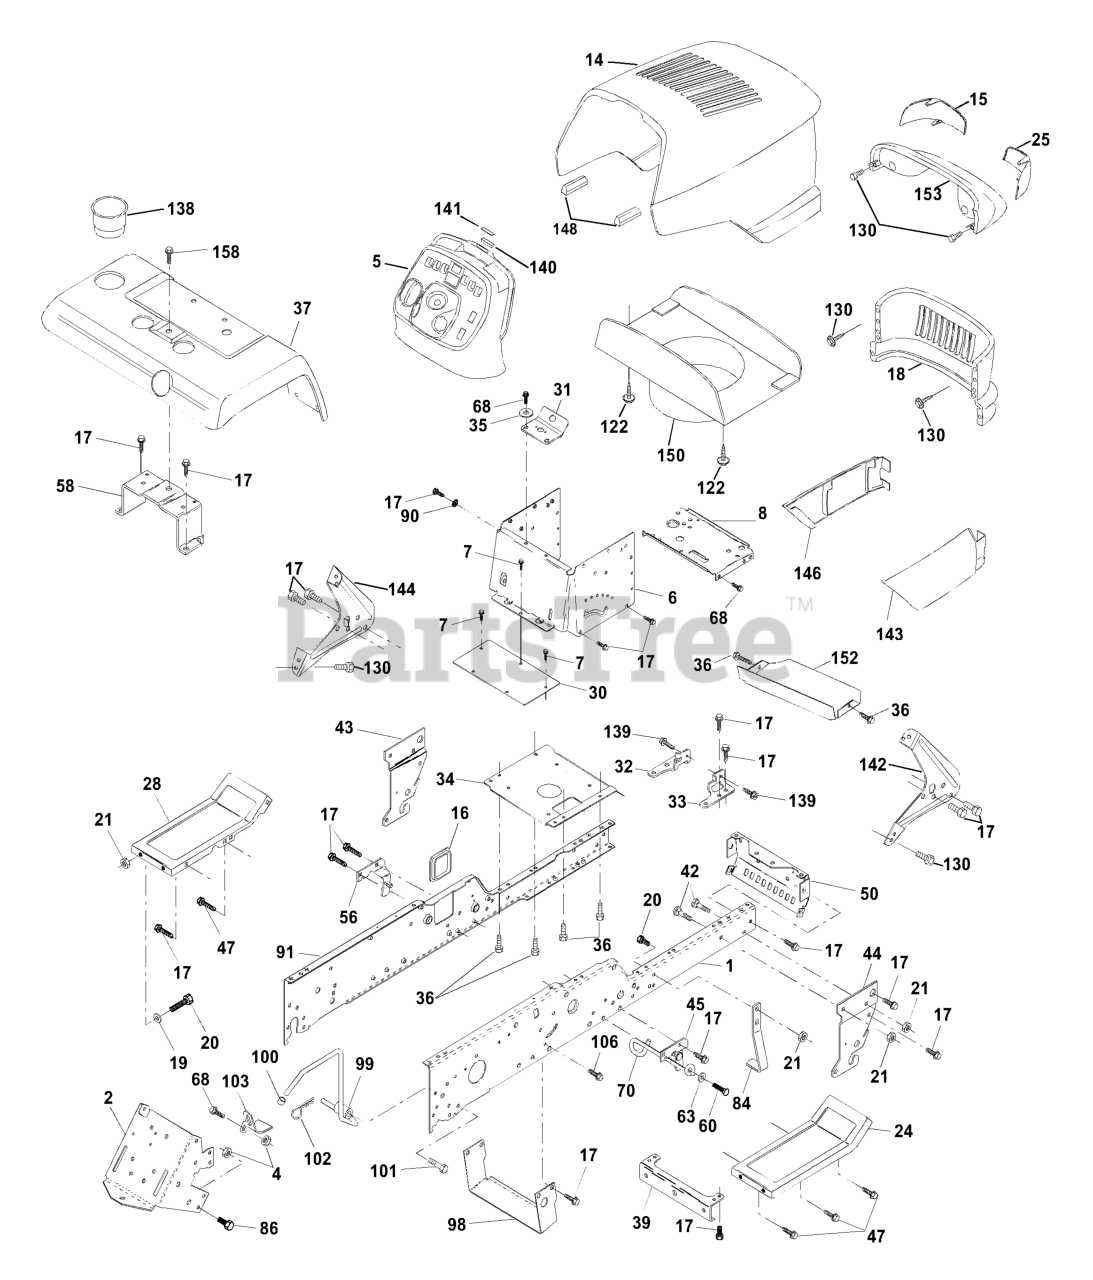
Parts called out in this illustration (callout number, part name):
1	RAIL, FRAME RH
2	DRAWBAR, GT
4	Nut, Lock Hex 7/16 Unc
5	DASH.STEALTH.YTGT.2CYL.BLK
6	DASH VGT, LOWER
7	SCREW
8	SUPPORT, BATTERY
14	HOOD ASM.
15	LENS LH
16	COVER ACCESS
17	SCREW 3/8-16X3/4
18	GRILLE
19	WASHER
20	BOLT
24	FOOTREST RH
25	LENS RH
28	FOOT REST LH
30	SADDLE.HYDRO.95
31	BRACKET SUPT 1-PC VGT STEERING
34	PLATE ASM ENG CHASSIS
35	WASHER
36	SCREW 5/16"
37	FENDER
39	BRACKET AXLE, FRONT
42	BOLT D
43	FRONT SUSPENSION BRKT LH
44	FRONT SUSPENSION BRKT RH
45	BRACKET SUSP RH
47	SCREW 3/8-16X1/2
50	BRACKET, CHASSIS FRONT
56	BRACKET ASM, SUSP CHASSIS
58	BRACKET ASM, FENDER
60	SCREW.3/8-16
63	WASHER
68	Screw, 5/16-18 x 1/2
70	KEEPER, BELT VGT GROUND
84	MOWER STOP
86	BOLT
90	LOCKWASHER
91	RAIL, FRAME LH
98	BRKT, CHASSIS SKID
99	ROD ASMBLY BYPASS
100	PLUNGER CAP
101	SCREW LT
102	RETAINER M
103	BRACKET LOCK BYPASS
106	SCREW
122	SCREW.HEX.WS.HD.8-18 X 7/8
130	SCREW
135	SCREW 3/8-16X1/2
138	CUPHOLDER
139	BOLT, SHOULDER 5/16-18
140	MAGNET STEALTH
141	STRIKER PLATE
142	BRACKET DASH STEALTH(R)
143	SKIRT GRILLE RH
144	BRACKET DASH STEALTH LH
146	SKIRT GRILLE LH
148	EXTRUSION BUMPER (3 2) (2 2)
150	DUCT HEAT HOOD
152	BROWNING SHIELD
153	LENS, HEADLIGHT BAR
158	SCREW 3/8-16X1/2
